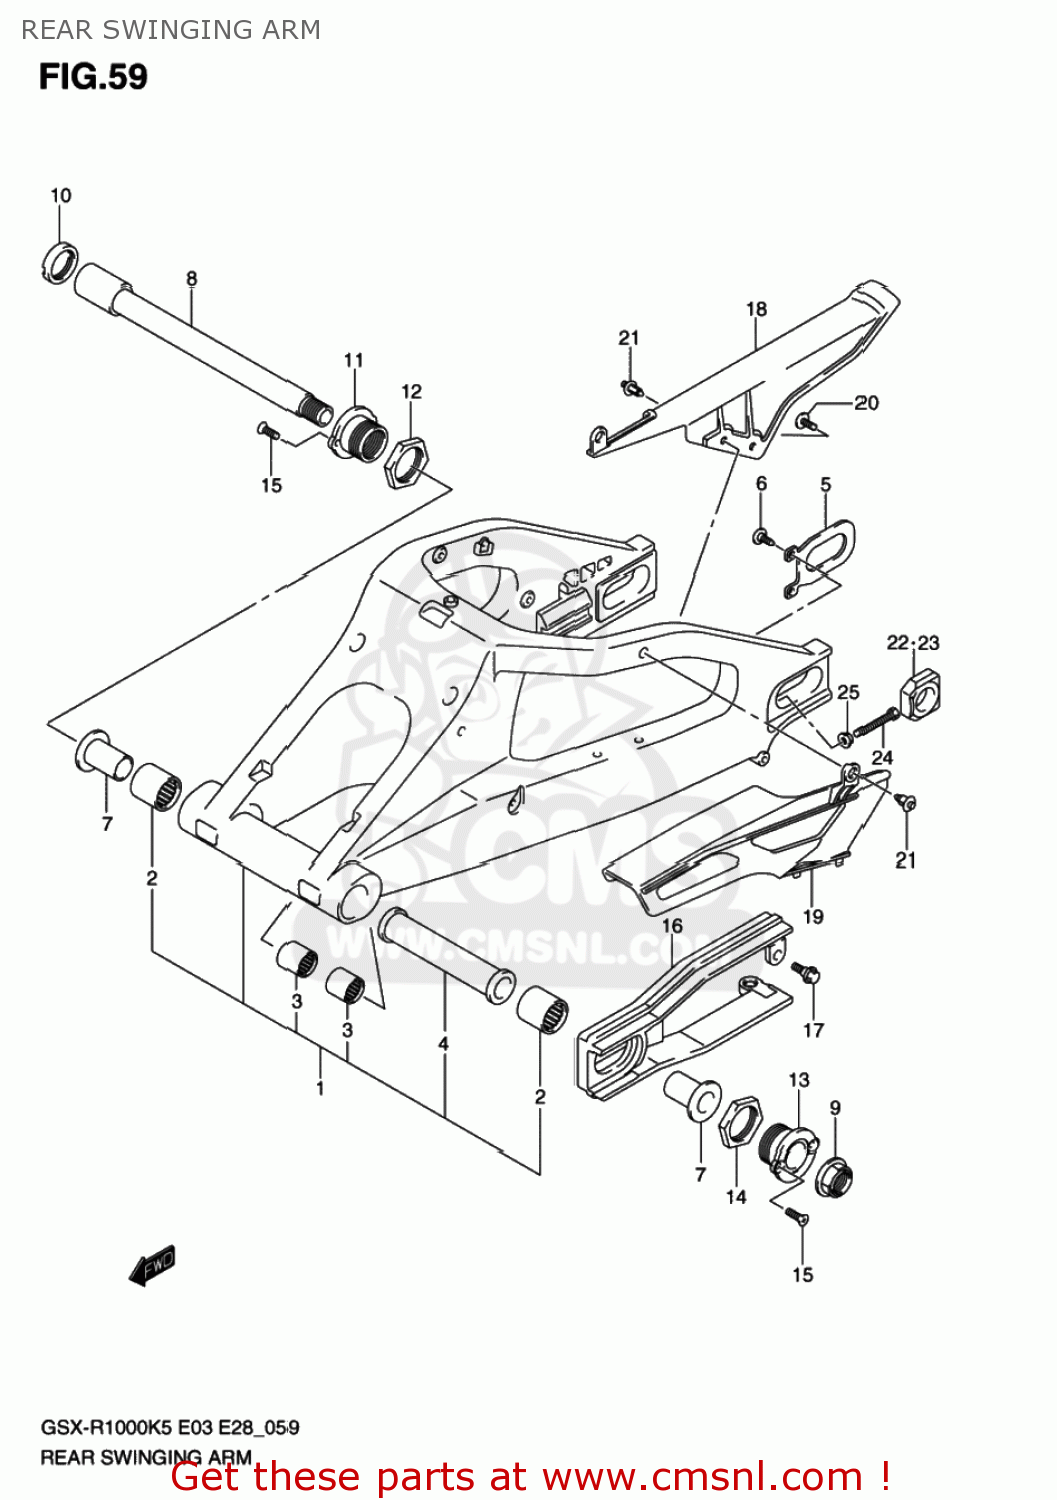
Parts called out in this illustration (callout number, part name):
1	SWINGINGARM ASSY,RR
2	BEARING(27X35X35)
3	BEARING(17X24X20)
4	SPACER,RR SWG PVT CTR
5	PLATE,RR SWING ARM BRKT
6	SCREW(6X16)
7	SPACER,RR SWGARM PIVOT BEARING
8	SHAFT,RR SWINGINGARM PIVOT
9	NUT
10	NUT,REAR SWGAR
11	BOSS, RR SWGARM PIVOT, L
12	NUT,RR SWGARM PIVOT BOSS,R
13	BOSS, RR SWGARM PIVOT, L
14	NUT,RR SWGARM PIVOT BOSS,L
15	SCREW
16	BUFFER,CHAIN TOUCH DEFENSE
17	BOLT(6X17.8)
18	CASE,CHAIN NO.
19	CASE,CHAIN NO.2
20	SCREW(6X16)
21	CLIP(BLACK)
22	ADJUSTER,CHAIN
23	ADJUSTER,CHAIN
24	BOLT(8X50)
25	NUT
